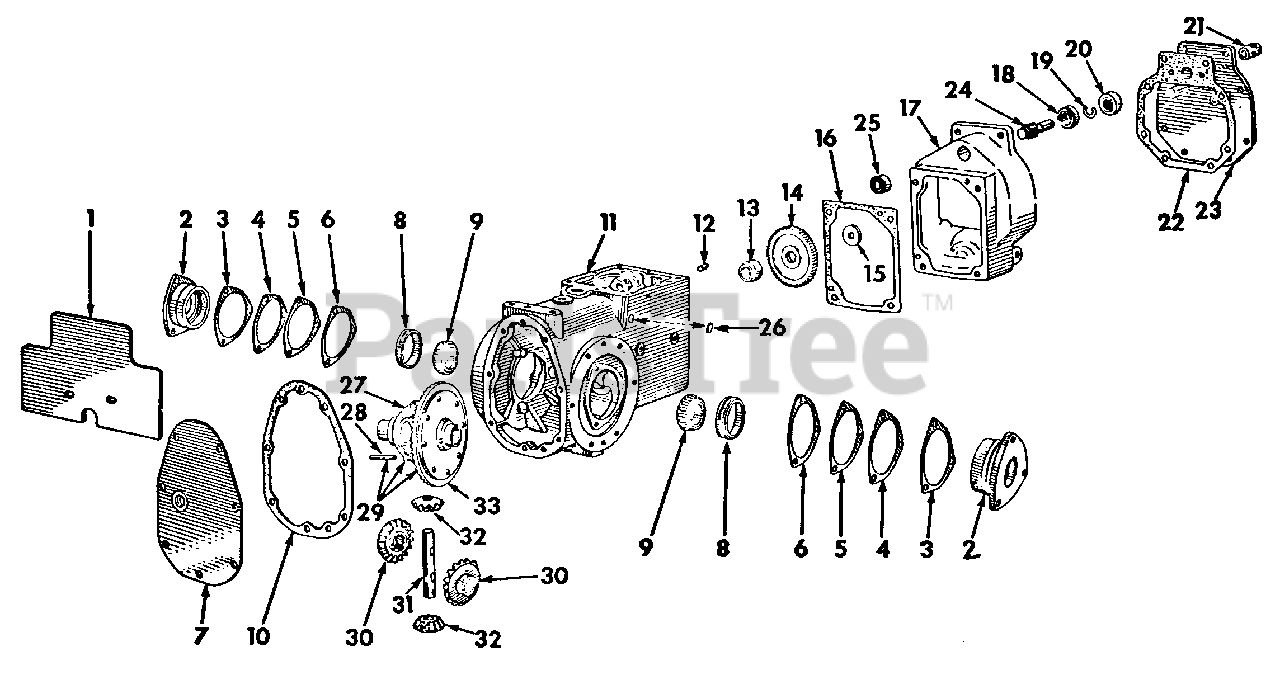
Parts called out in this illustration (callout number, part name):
1	Not used in this application
2	Cage w/Cup IH-ST974, Differential Brg
3	Shim, Differential Brg Retainer, .004
4	Shim, Differential Brg Retainer, .007
5	Shim, Differential Brg Retainer, .0149
6	Shim, Differential Brg Retainer, .0299
7	Plate Assy, Transmission Case Rear Cover
8	Bearing, Differential Cup
9	Bearing Assy, Differential Cone
10	Gasket, Transmission Case Rear Cover Plate
11	Case Assy, Transmission
12	Dowel, Transmission Case to Reduction Housing
13	Spacer, Driven Reduction
14	Gear, Reduction Drive -84T
15	Washer, 15/32 x 1-1/4 x 3/16
16	Gasket, Reduction Drive Housing
17	Housing, Reduction Drive
18	Bearing Assy, Reduction Drive Shaft Front Ball
19	Ring, Reduction Drive Shaft Brg Ext Snap
20	Seal, Reduction Drive Shaft Oil
21	Bushing, Clutch Shaft
22	Gasket, Reduction Housing Cover Plate
23	Plate Assy, Reduction Housing Cover
24	Shaft, Reduction Drive
25	Bearing Assy, Reduction Drive Shaft Rear
26	Plug, 11/16 Expansion
28	Pin, Differential Pinion Shaft Lock
29	Case w/Drive Gear, Differential
30	Gear, Differential Side
31	Shaft, Differential Pinion
32	Pinion, Differential -10T
33	Gear, Differential Drive -46T
